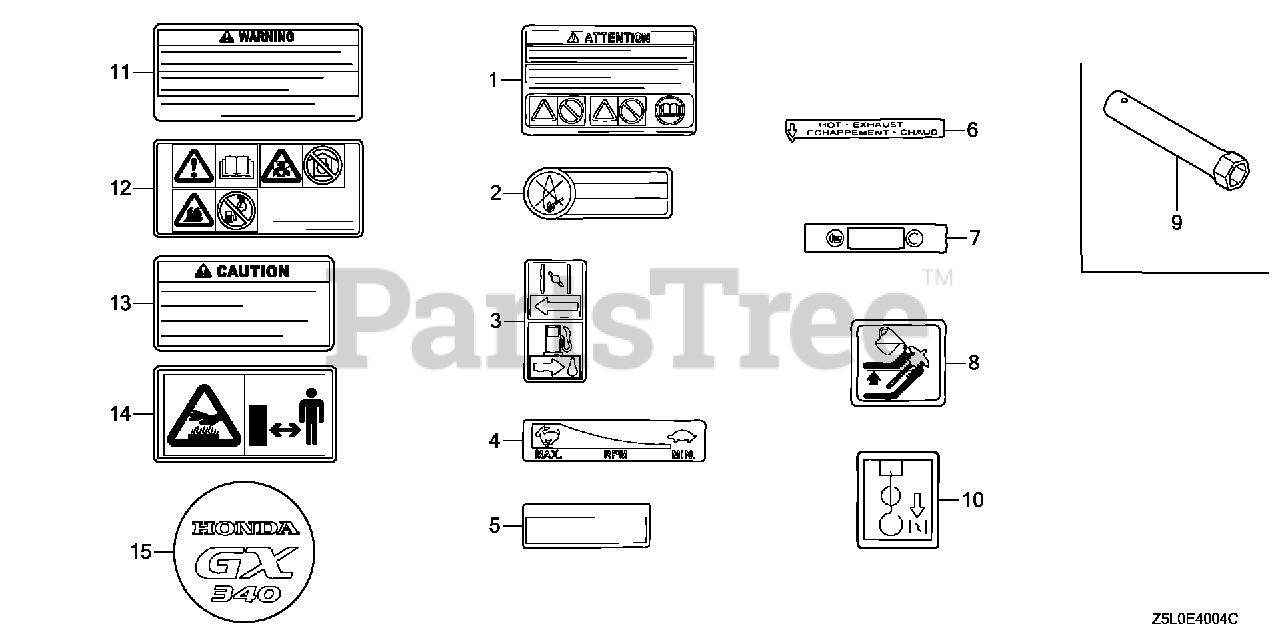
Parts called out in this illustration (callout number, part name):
5	MARK, AIR CLEANER (ENGLISH)
9	WRENCH, PLUG
10	MARK, CHOKE
11	MARK, OPERATOR CAUTION (FRENCH)(MADE IN JAPAN)
12	MARK, OPERATOR CAUTION (PICTOGRAPH)
